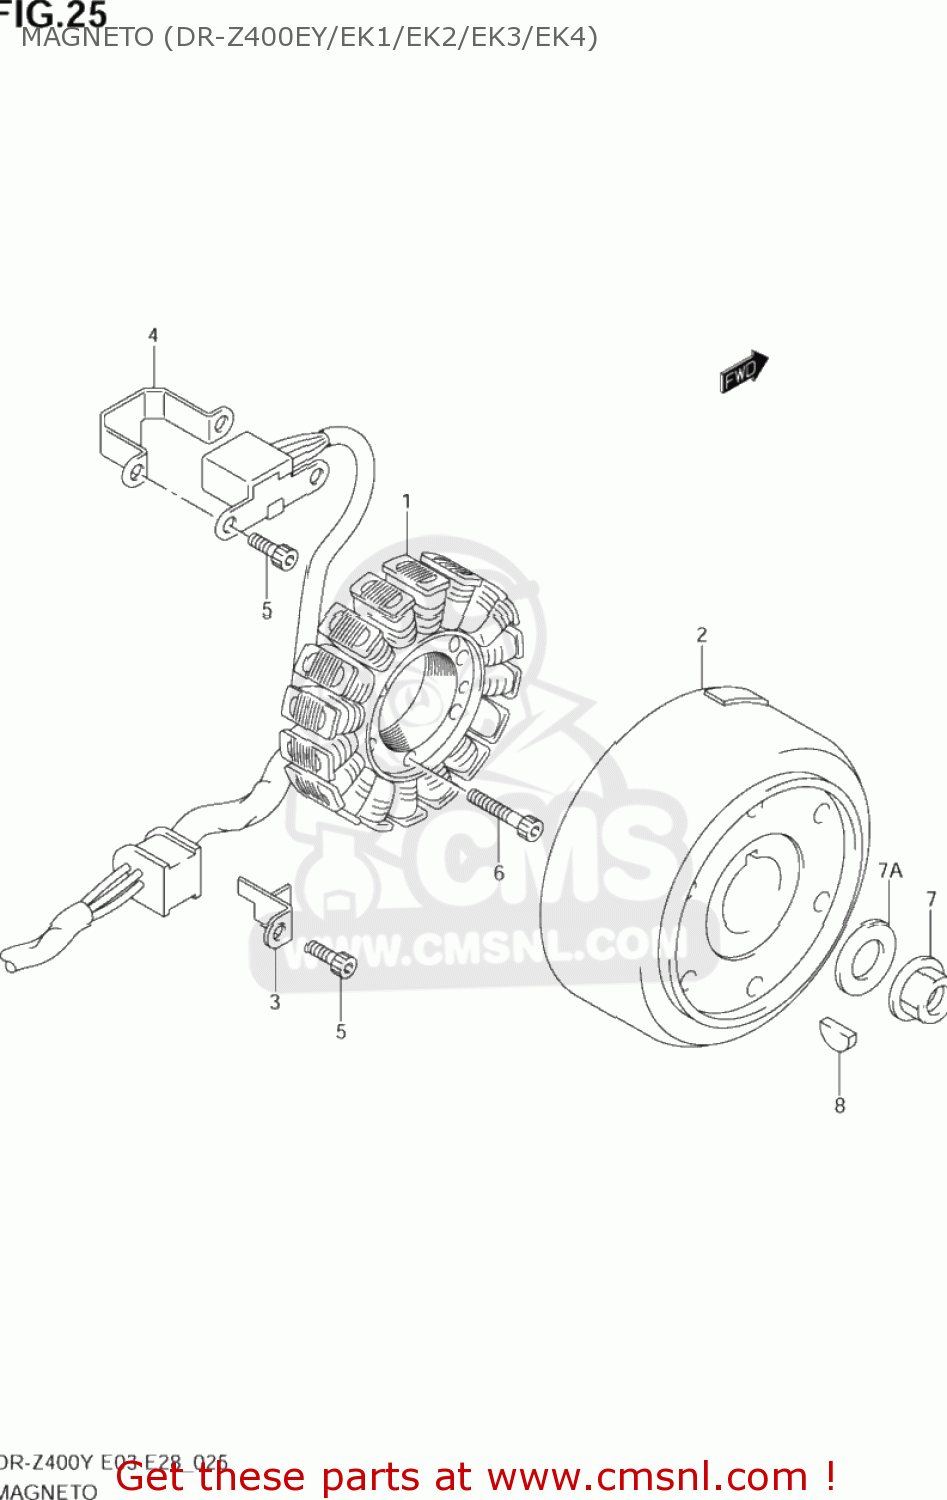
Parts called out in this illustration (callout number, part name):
1	STARTER ASSY
2	ROTOR ASSY
3	CLAMP,MAGNETO LEAD NO.1
4	CLAMP,MAGNETO LEAD WIRE
5	BOLT
6	BOLT
7	NUT
7A	WASHER(12X27X2)
8	KEY
